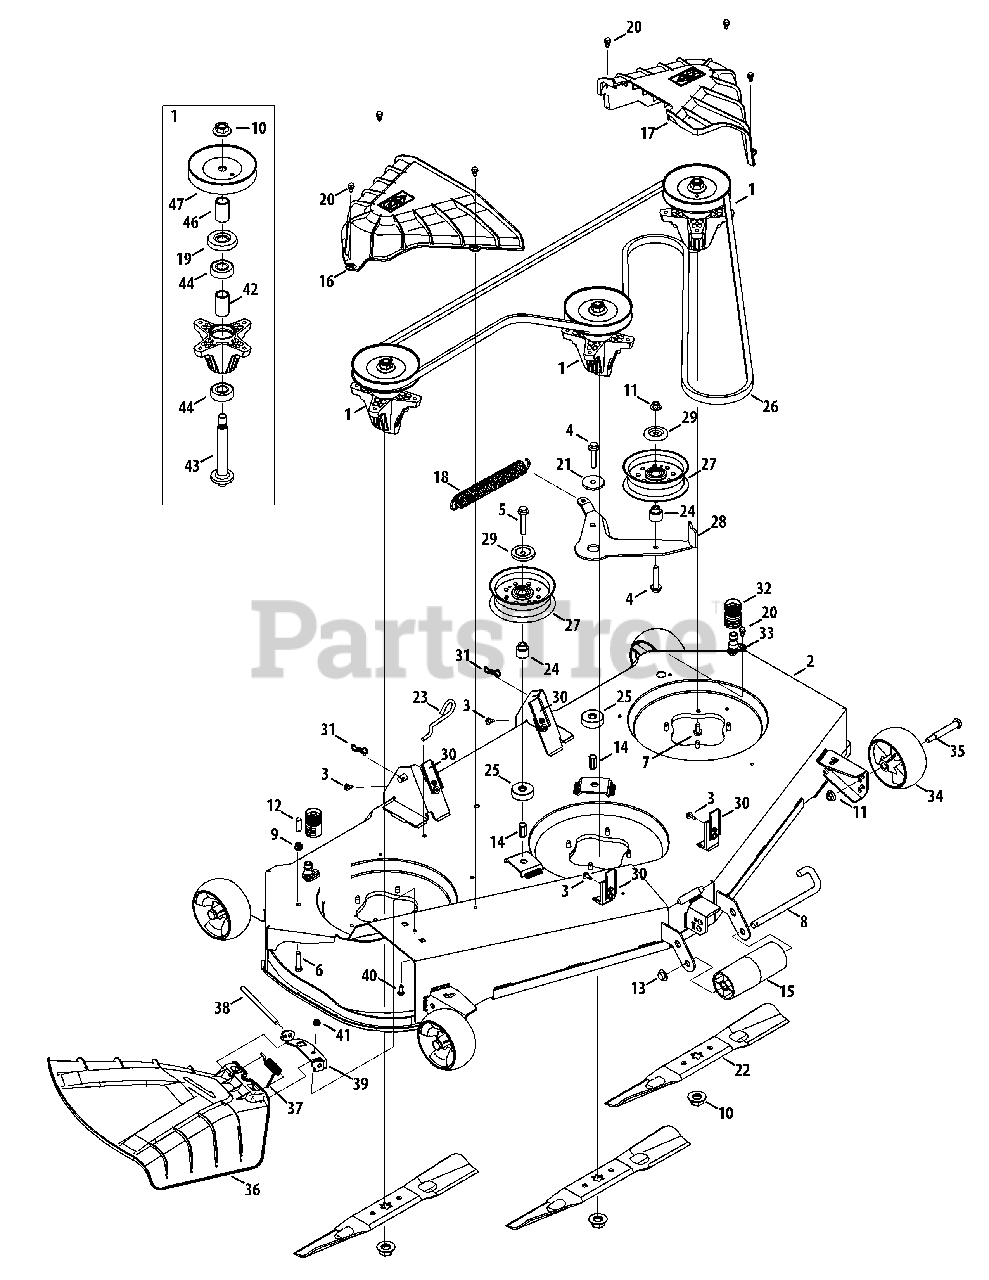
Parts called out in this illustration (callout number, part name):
1	Spindle Ass’y, Pulley, 5.37 Dia
2	Deck, 54"
3	Screw, M6-1 x .625
4	Hex Cap Screw, 3/8-16 x 2.00
5	Hex Cap Screw, 3/8-16 x 2.75
6	Hex Cap Screw, 5/16-18 x 1.50
7	Screw, Self-tapping, 5/16-18, 0.750,
8	Roller Pin, 1/2 x 7.31 Lg
9	Nut, Flange Lock, 5/16-18, Nylon
10	Nut, Flange, 5/8-18
11	Flange Lock Nut, 3/8-16
12	Vinyl Cap, .29 x 1.00
13	Push Cap, 1/2"
14	Rivet Nut, 3/8-16
15	Front Roller
16	Belt Cover, RH
17	Belt Cover, LH
18	Spring, Extension, 1.25 OD x 8.5
19	Bearing Shield
20	Shoulder Screw, 1/4-20 x 0.50
21	Shoulder Spacer, .970 x .190
22	Blade, Cut, 18.67" 2-In-1, Cub
23	Deck Spring Rod
24	Shoulder Spacer
25	Spacer, .385 ID x 1.75 OD x .585
26	Belt, V-Type, B Sec x 139
27	Pulley, Idler, 4.50" Dia.
29	Pulley Cap
30	Bracket, Lift, Stop
31	Bow-Tie Cotter Pin
32	Coupler, Water
33	Deck Wash Nozzle
34	Wheel, Deck, 5.0 Dia. Ball
35	Bolt, Shoulder, .496 x 2.50, 3/8-16
36	Chute Deflector Assembly
37	Spring, Torsion, .440 ID x 1.75
38	Hinge Pin
40	Hex Cap Screw, 1/4-20 x .62
41	Nut, Flange Lock, 1/4-20, Nylon
42	Pulley, Deck, 4.50 Dia.
43	Shaft, Spindle, 6.11
44	Bearing, Ball, .787id x 1.85 Od x .551
45	Spacer, .792 x 1.060 x 1.860
46	Spacer, .792 x 1.060 x 1.782
